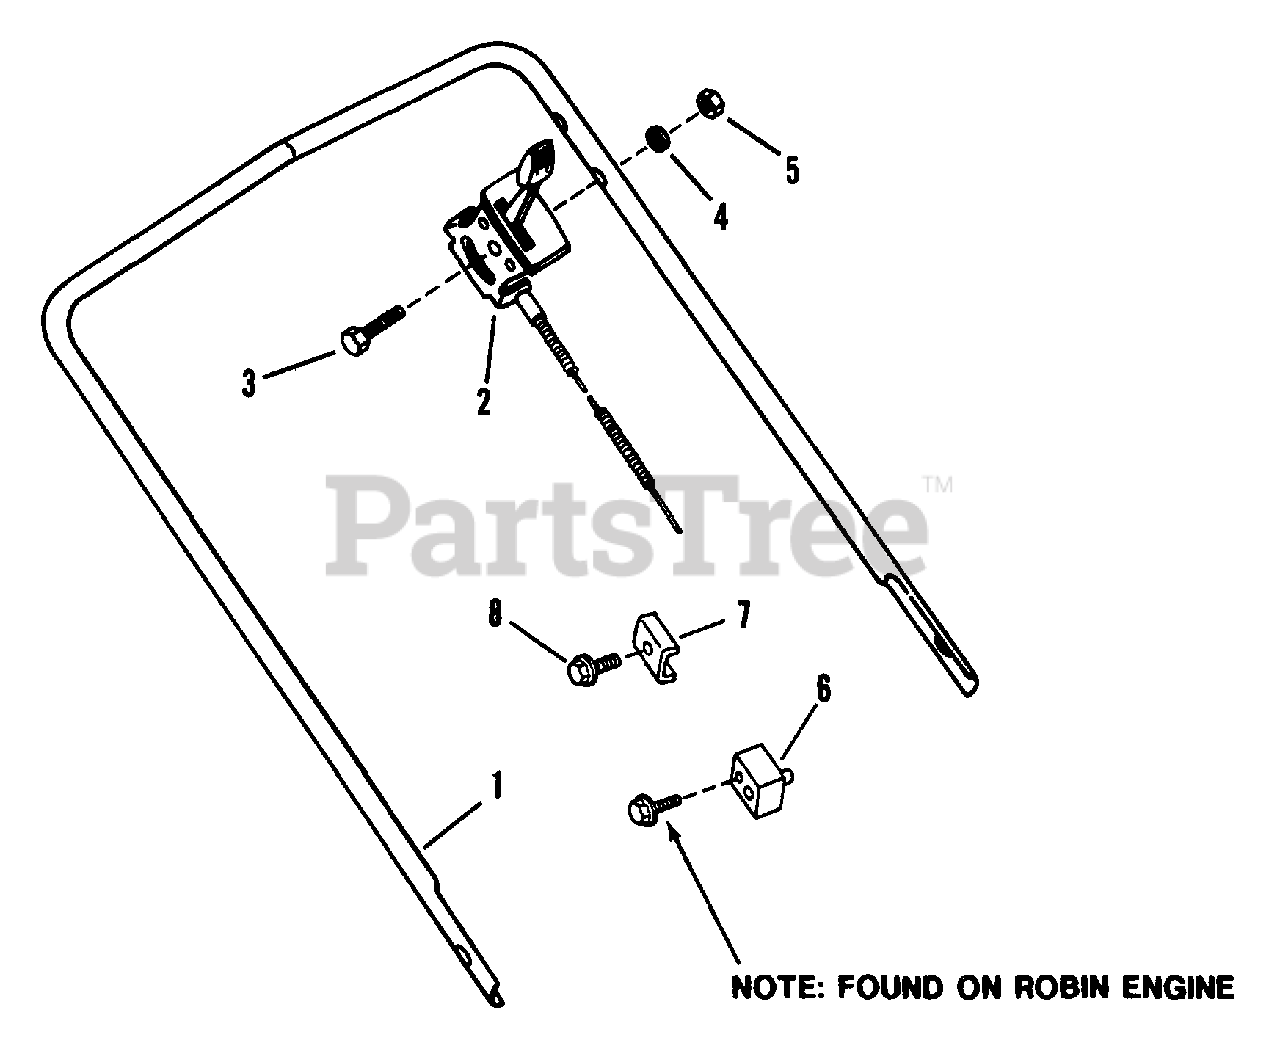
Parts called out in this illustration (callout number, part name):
1	HANDLE, Upper
2	THROTTLE, Control
3	SCREW, 1/4-28 x 1 3/4" Hex Head Cap
4	WASHER, 1/4 Internal Tooth Lock
5	NUT, 1/4-28 Hex
6	SPACER
7	CLAMP, Casing
8	SCREW, #10-18 x 5/8" Self-Tapping
